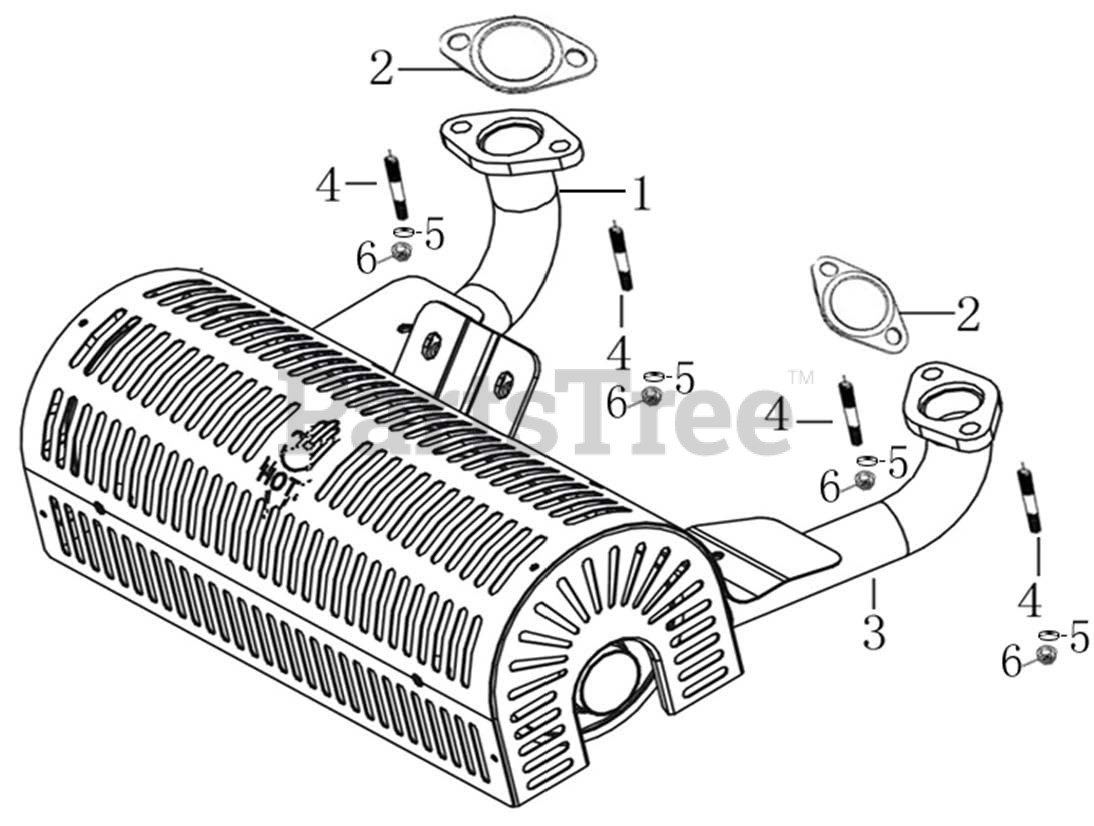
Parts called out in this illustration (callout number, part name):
1	OUTLET PIPE
2	GASKET, MUFFLER LONCIN
3	OUTLET PIPE
5	ELASTIC WASHER
6	HEXAGON NUT
